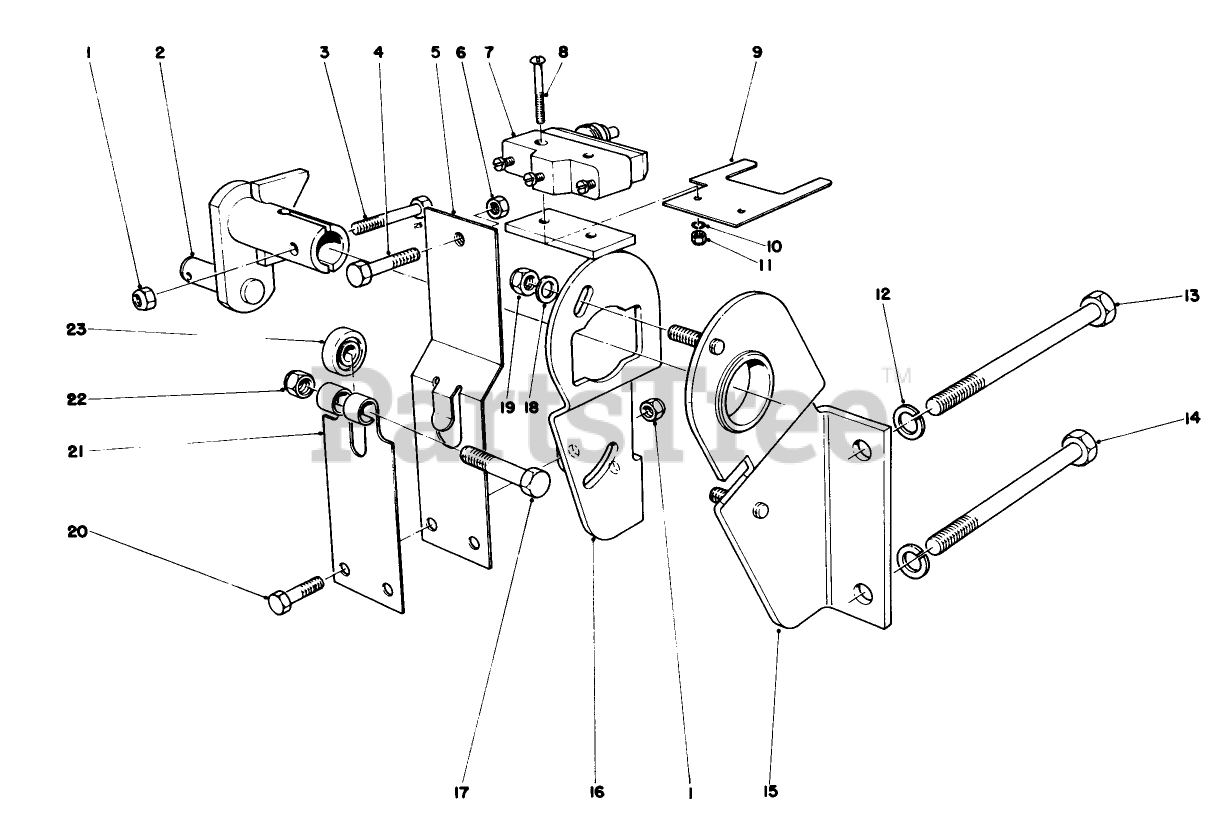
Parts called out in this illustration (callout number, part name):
1	NUT-LOCK, NI
2	Lever-Pump
3	SCREW-HH
4	SCREW-HH
5	EXTENDED LEAF SPRING ASM
6	NUT-HEX
7	Micro Switch
8	SCREW-MACHINE
9	STOP-SPRING, LEAF
10	WASHER-LOCK, INTERNAL
11	NUT-HEX
12	WASHER-LOCK
13	SCREW-HH
14	SCREW-HH
15	MTG BRKT WA B
16	PUMP PLATE WA B
17	SCREW-HH
18	Washer-Thrust
19	NUT-LOCK
20	SCREW-HH
21	SPRING-LEAF
22	NUT-LOCK, NI
23	BEARING-BALL
